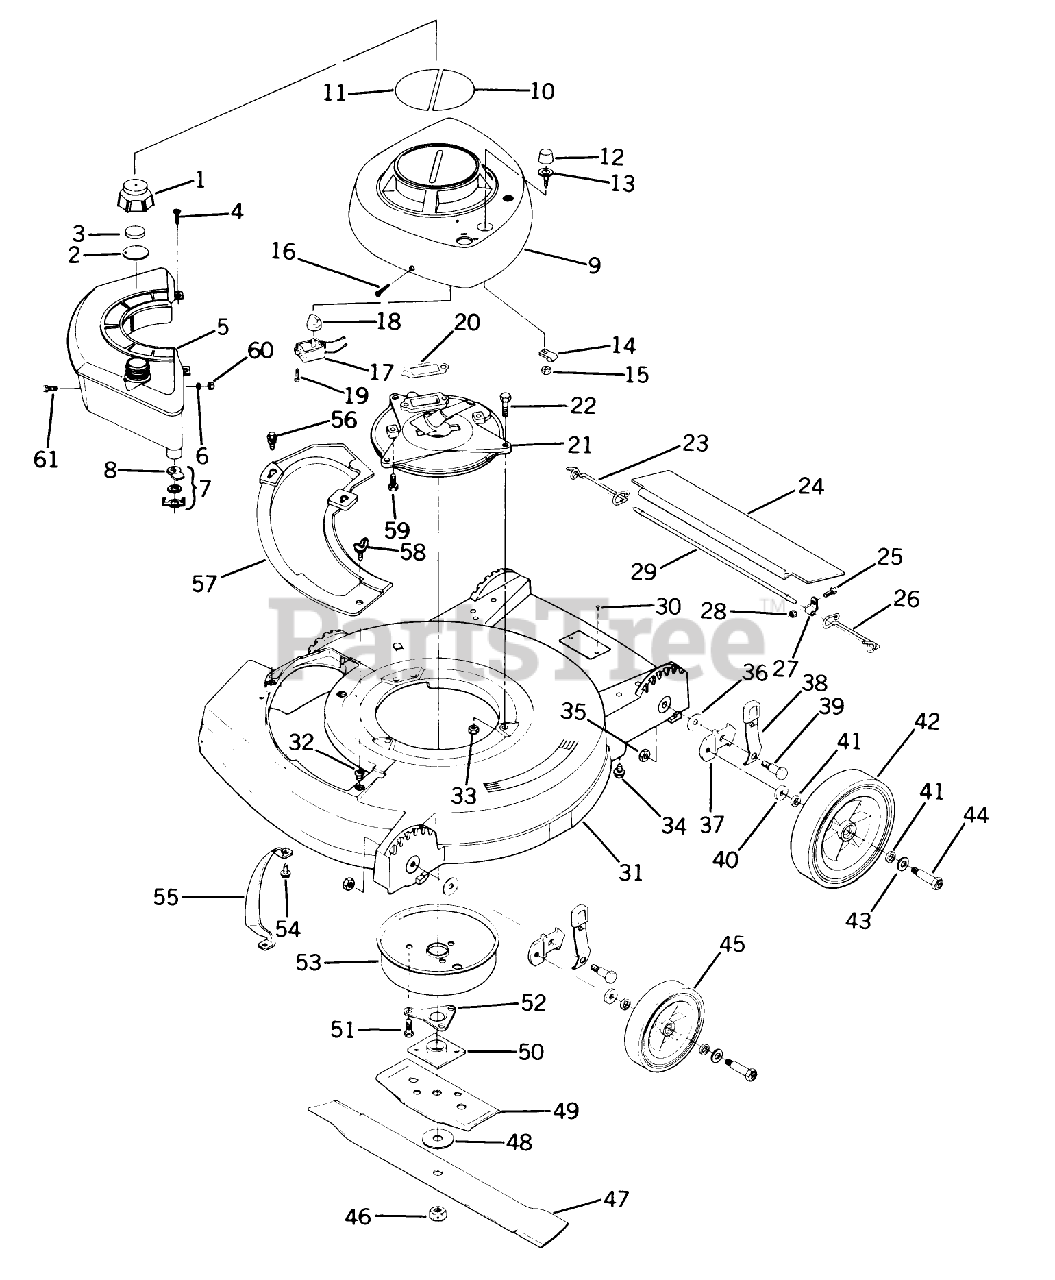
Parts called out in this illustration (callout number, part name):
2	GASKET S
3	BAFFLE - FOAM SM
4	SCREW F
7	SHUT OFF VALVE KIT
15	LOCKNUT S
16	SCREW F
18	SWITCH KNOB
22	SCREW
23	SPRING;TRAILING SHIELD RH
24	TRAILING SHIELD-19
24	SHIELD
26	SPRIG T/SHLD ASOC
27	CLAMP ROD KMC
28	LOCKNUT E
29	ROD T/SHIELD ADV WIRE
29	ROD 21" ADVANCE
33	NUT-LOCK F
34	SCREW
35	LOCKNUT
36	WASHER
40	WASHER WROUGHT
41	WASHER
43	SPACER
44	BOLT WHEEL
45	WHEEL & TIRE KIT
46	NUT-BLADE
48	WASHER
50	PLATE AND COLLAR ASM
51	SCREW
52	SUPPORT F
55	TOE BAR 19"
55	BAR-TOE
58	WING SCREW LAWRE
59	SCREW V
